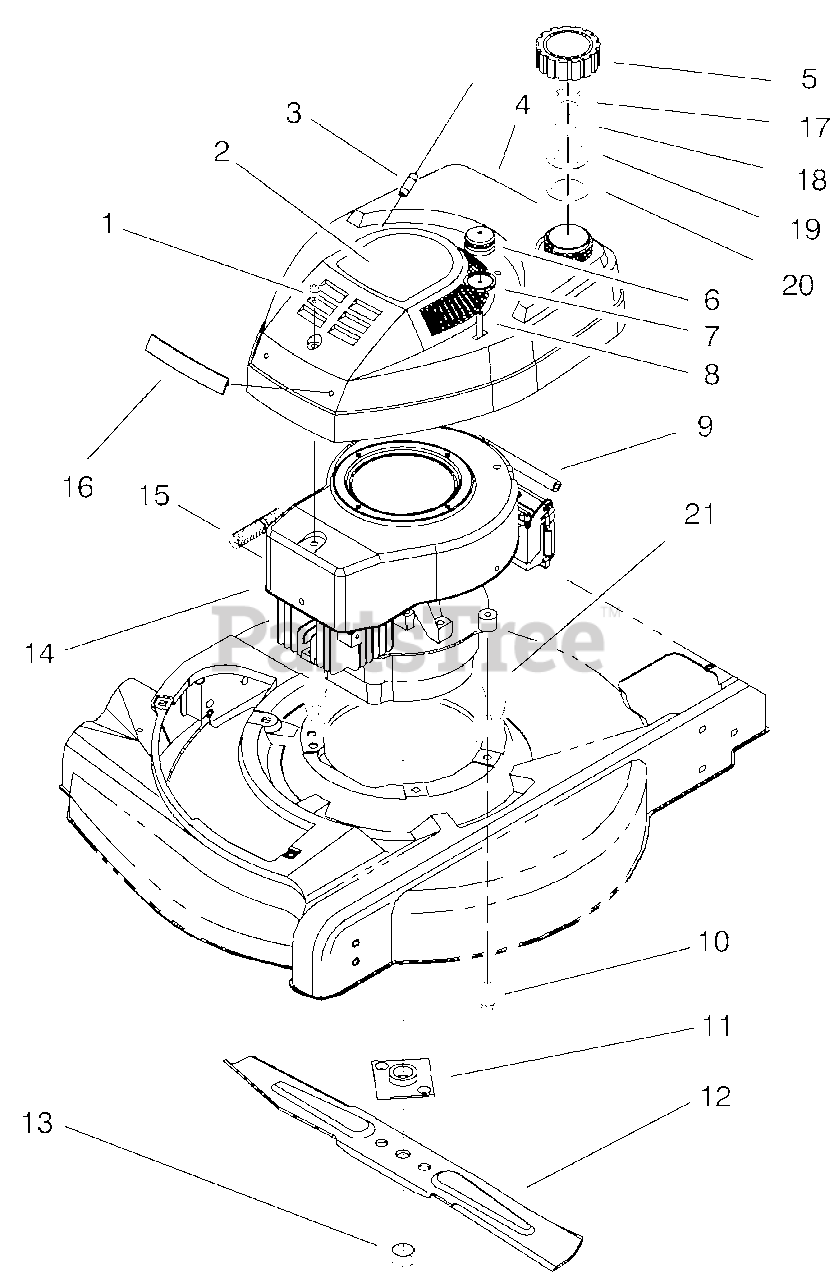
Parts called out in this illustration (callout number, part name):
1	Screw-Sems
2	Decal-Shroud
3	Rope-Stop
4	Tank & Shroud Assembly
5	Gas Cap Assembly (Incl. Ref. #17-20)
6	Bulb-Primer
7	Body-Primer
8	Hose-Primer
9	Line-Gas
10	Screw-Engine
11	Plate & Collar Assembly
12	Blade-21"
13	Nut-Blade
14	Engine
15	Spring-Compression
16	Applique-Shroud
18	Baffle-Foam
21	Plate-Engine
